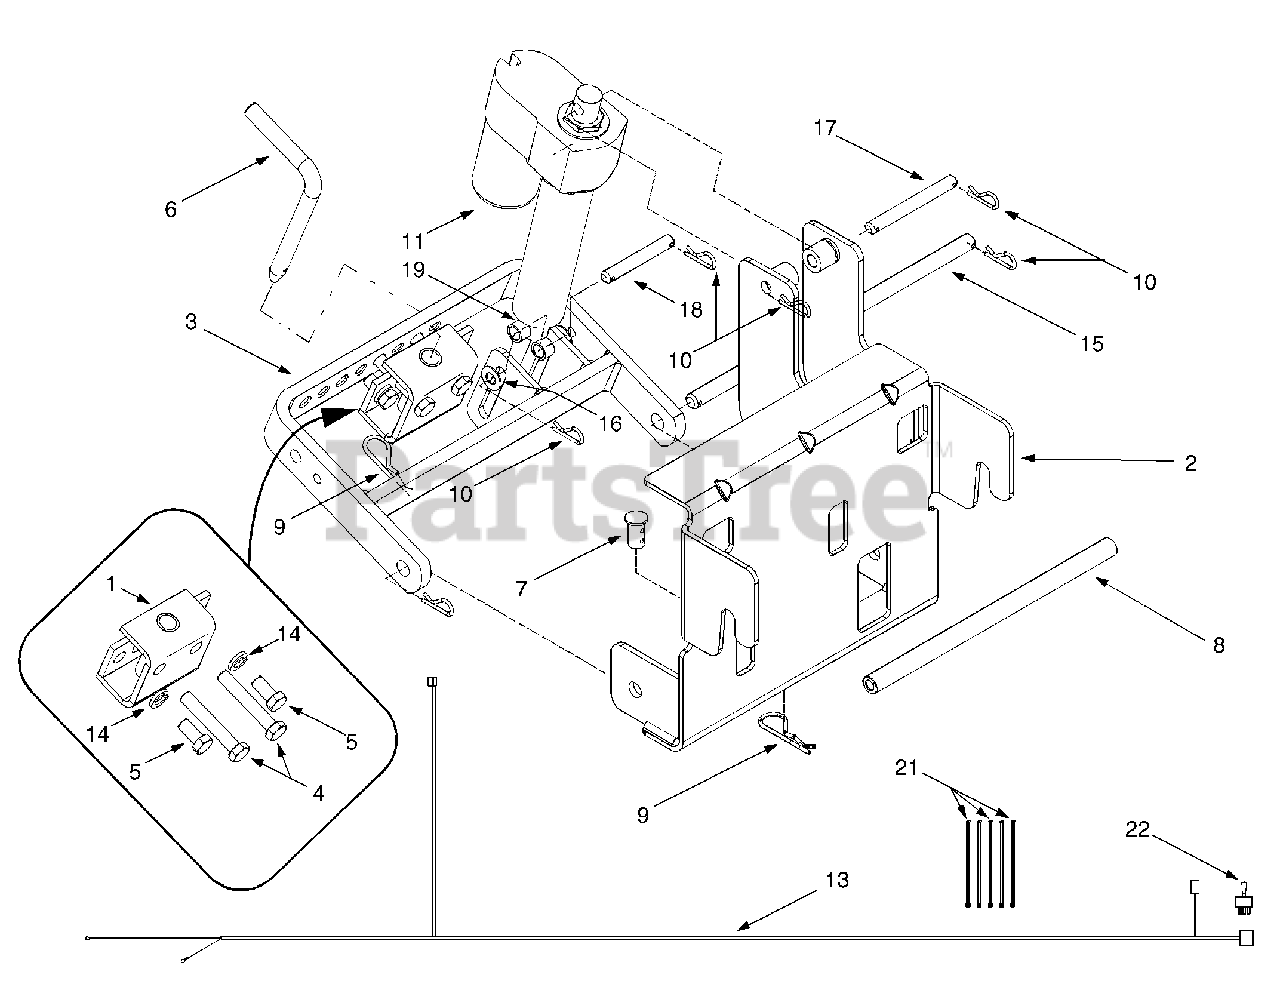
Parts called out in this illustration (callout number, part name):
5	Hex Cap Screw, 1/2-13 x 1 (Grade 5)
6	Hitch Pin
7	Clevis Pin
8	Support Rod, 3/4 x 13"
9	Internal Cotter Pin, .148 x 3
10	Internal Cotter Pin
11	Electromechanical Linear Actuator
13	Wire Harness
14	Lock Washer, 1/2
15	Hitch Rod
16	Flat Washer, .51 x 1.12 x .060
17	Upper Cylinder Support Rod
18	Lower Cylinder Support Rod
19	Spacer, .542 x .750 x .5
22	Toggle Switch
